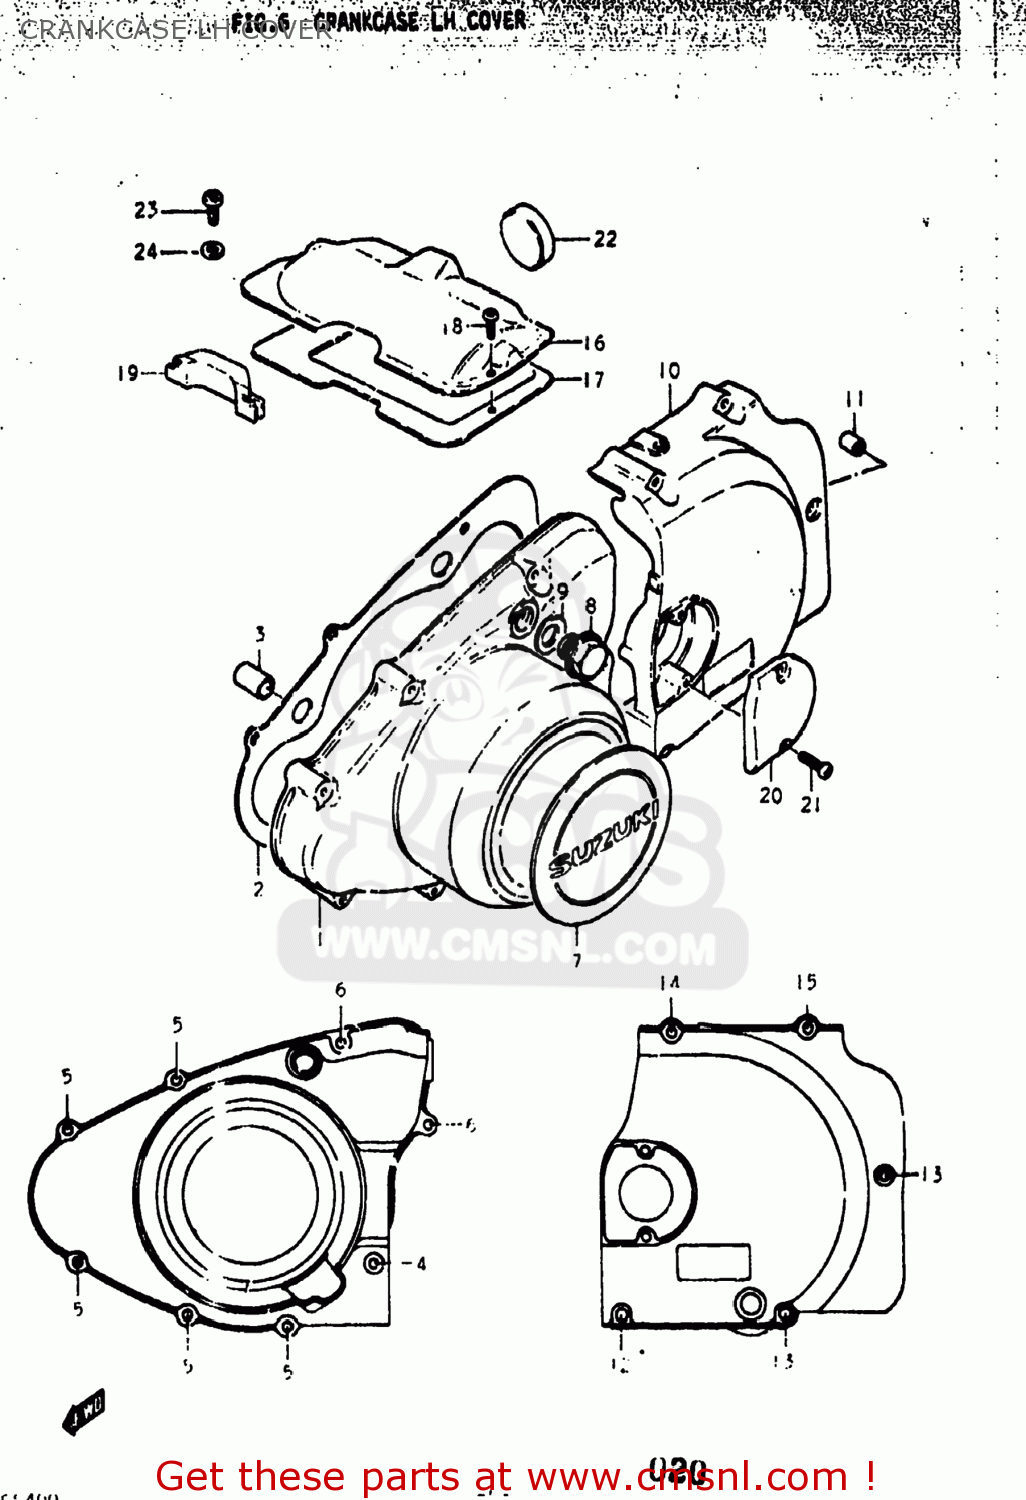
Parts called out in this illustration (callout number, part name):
1	COVER
2	GASKET,MAGNETO COVER (MCA)
3	PIN
4	SCREW
5	SCREW (6X35)
6	SCREW
7	EMBLEM
8	PLUG (14X12)
9	GASKET(14X19.2X2) (NAS)
10	COVER,SPROCKET
11	PIN
12	SCREW
13	SCREW 6X60
14	SCREW
15	SCREW
16	COVER,STARTER MOTOR
17	GASKET (MCA)
18	SCREW
19	GROMMET,STARTING MOTOR
20	CAP,CLUTCH RELEASE ADJUST
21	SCREW
22	PLUG
23	SCREW
24	GASKET(6.2X11X1) (NAS)
